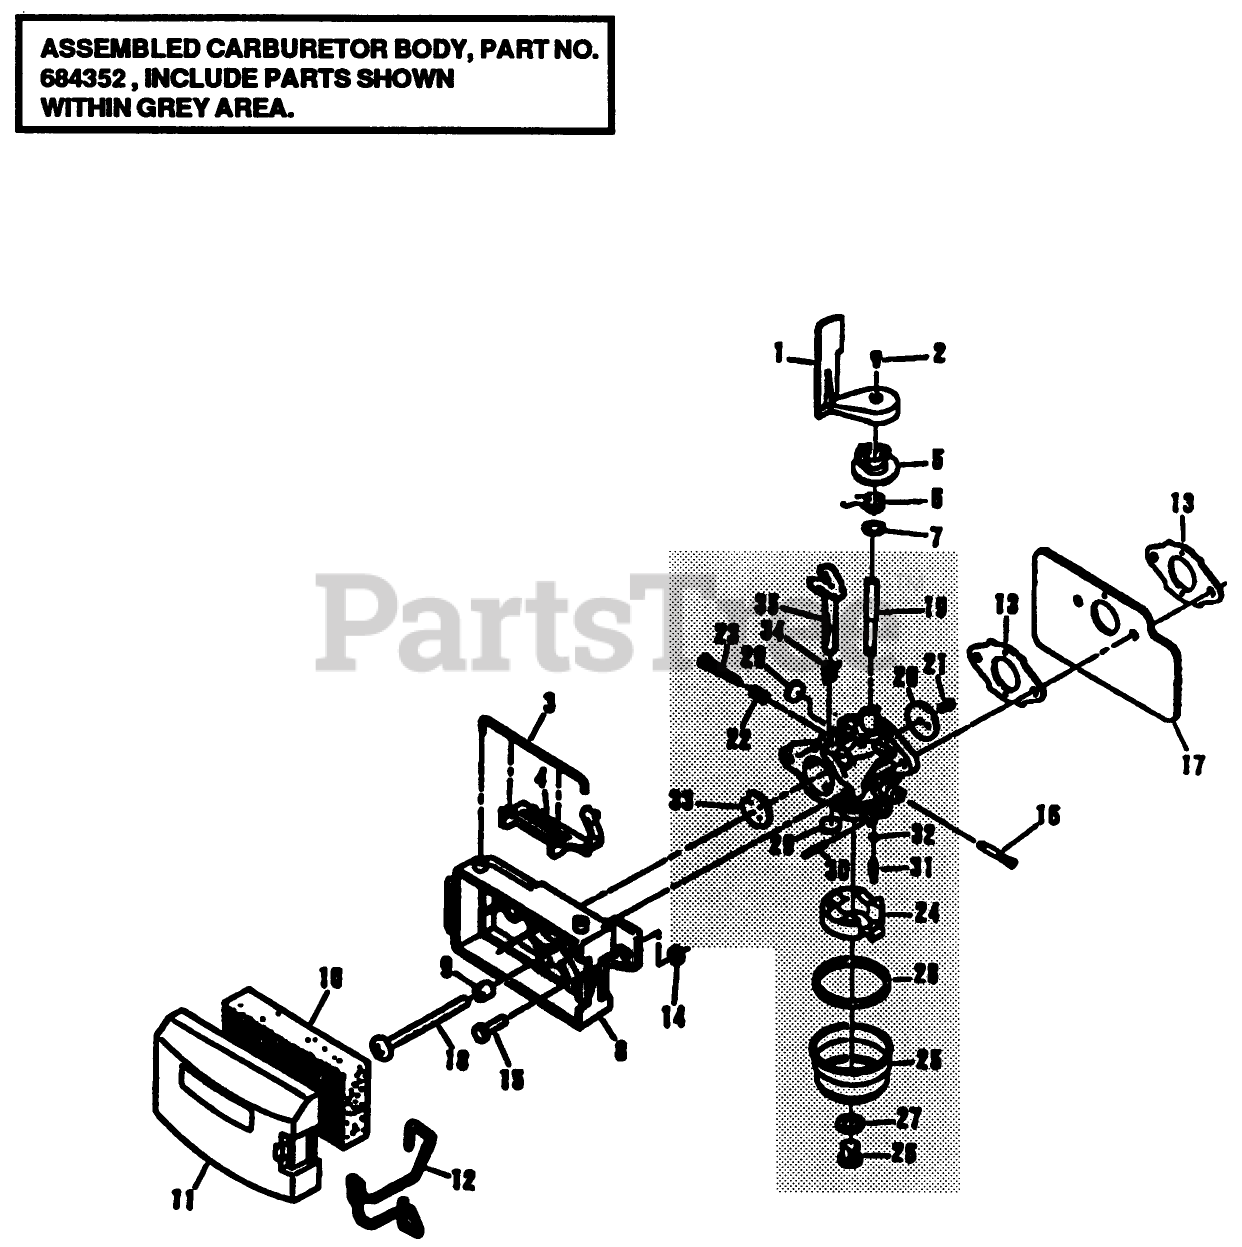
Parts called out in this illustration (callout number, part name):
1	AIR VANE F
2	SCREW F
3	RETAINER
5	COLLAR A/VAVE F
6	THROTTLE SPR E
7	WASHER VF
9	SPACER
12	RETAINER-COVER, FILTER
13	GASKET CARB S
15	SCREW
16	SCREEN FUEL PITTS
17	Heat Shield
18	SCREW
19	Throttle Shaft
20	Throttle Valve
21	Screw-Throttle Valve
22	Spring-Idle Needle
23	Idle Needle
25	Fuel Bowl
26	Screw-Bowl Retainer
27	Bowl Retainer Gasket
28	Fuel Bowl Gasket
29	Plug-Welch
30	Float Shaft
31	Inlet Needle Valve
32	Valve Seat
33	Choke Valve
34	Choke Return Spring
35	Choke Shaft
